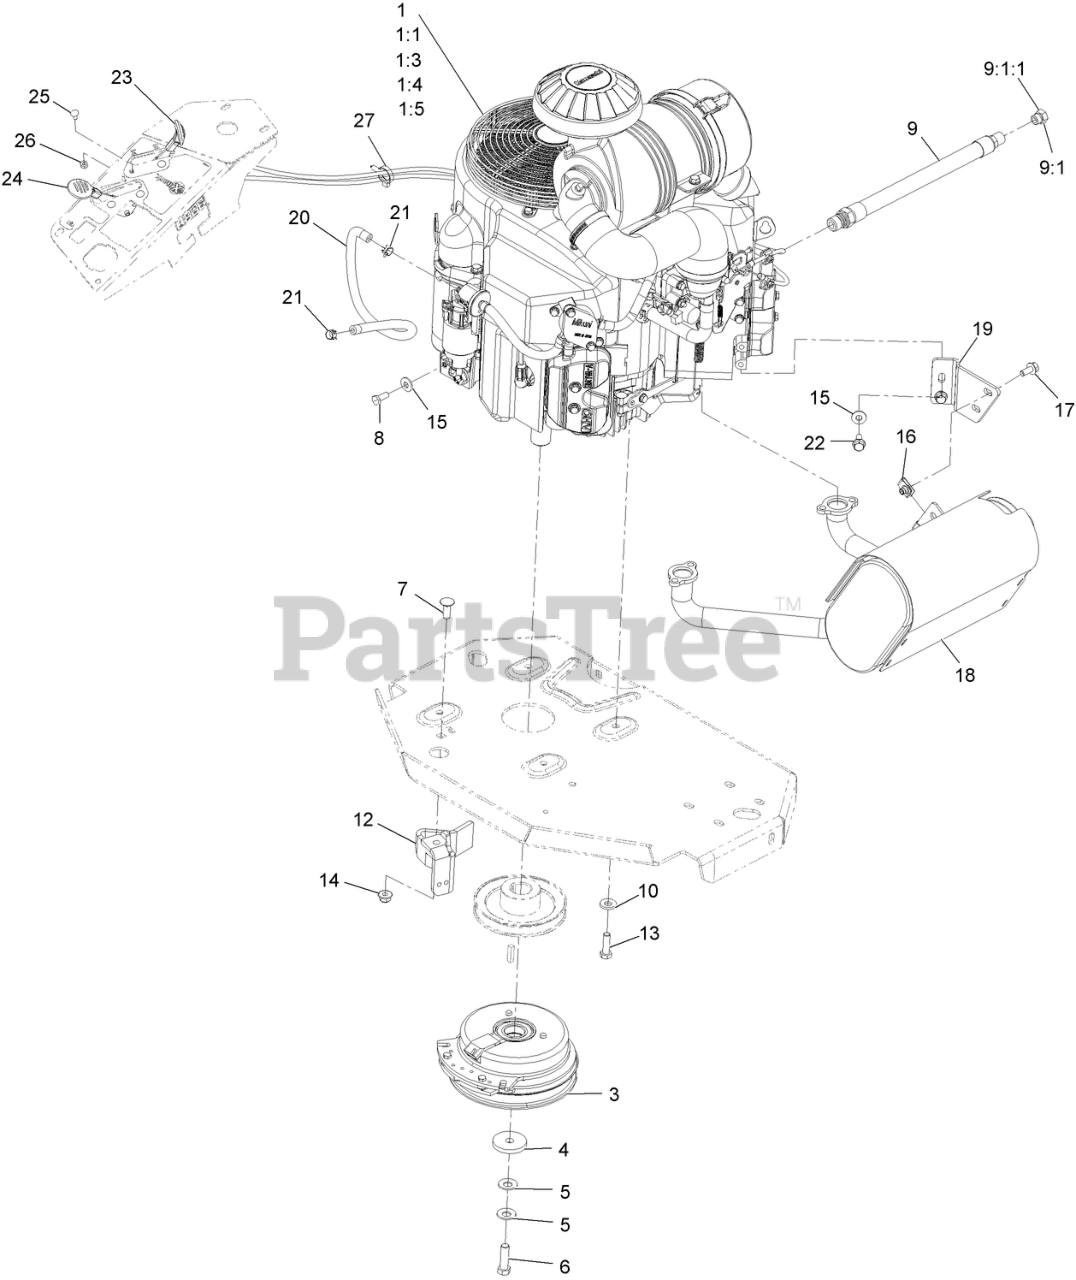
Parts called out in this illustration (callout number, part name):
1:1	Kawasaki 49065-2078 Engine Oil Filter
1:3	Kawasaki 49019-0031 Fuel Filter
1:4	Kawasaki 11013-7039 Safety Filter
1:5	Kawasaki 11013-7038 Air Filter
3	CLUTCH KIT
4	WASHER-CLUTCH
5	WASHER-SPRING
6	SCREW-HH 7/16-20 X 1 1/2 W/LOCTITE
7	SCREW-CARR
8	SCREW-HH
9	ENGINE OIL DRAIN HOSE ASM
9:1	PLUG-HH
9:1:1	O-RING
10	WASHER-BELLEVILLE
12	CLUTCH-ANCHOR
13	SCREW-HH
14	NUT-HF, NI
15	WASHER-SPRING
17	SCREW-HHF
18	KIT, MUFFLER
19	BRACKET-MUFFLER
20	HOSE-FUEL
21	CLAMP-HOSE
22	SCREW-HHF
23	ASM, CHOKE CABLE
24	ASM,THROTTLE CABLE
25	BOLT-CARR
26	NUT-LOCK, NI
27	CLAMP-HOSE
